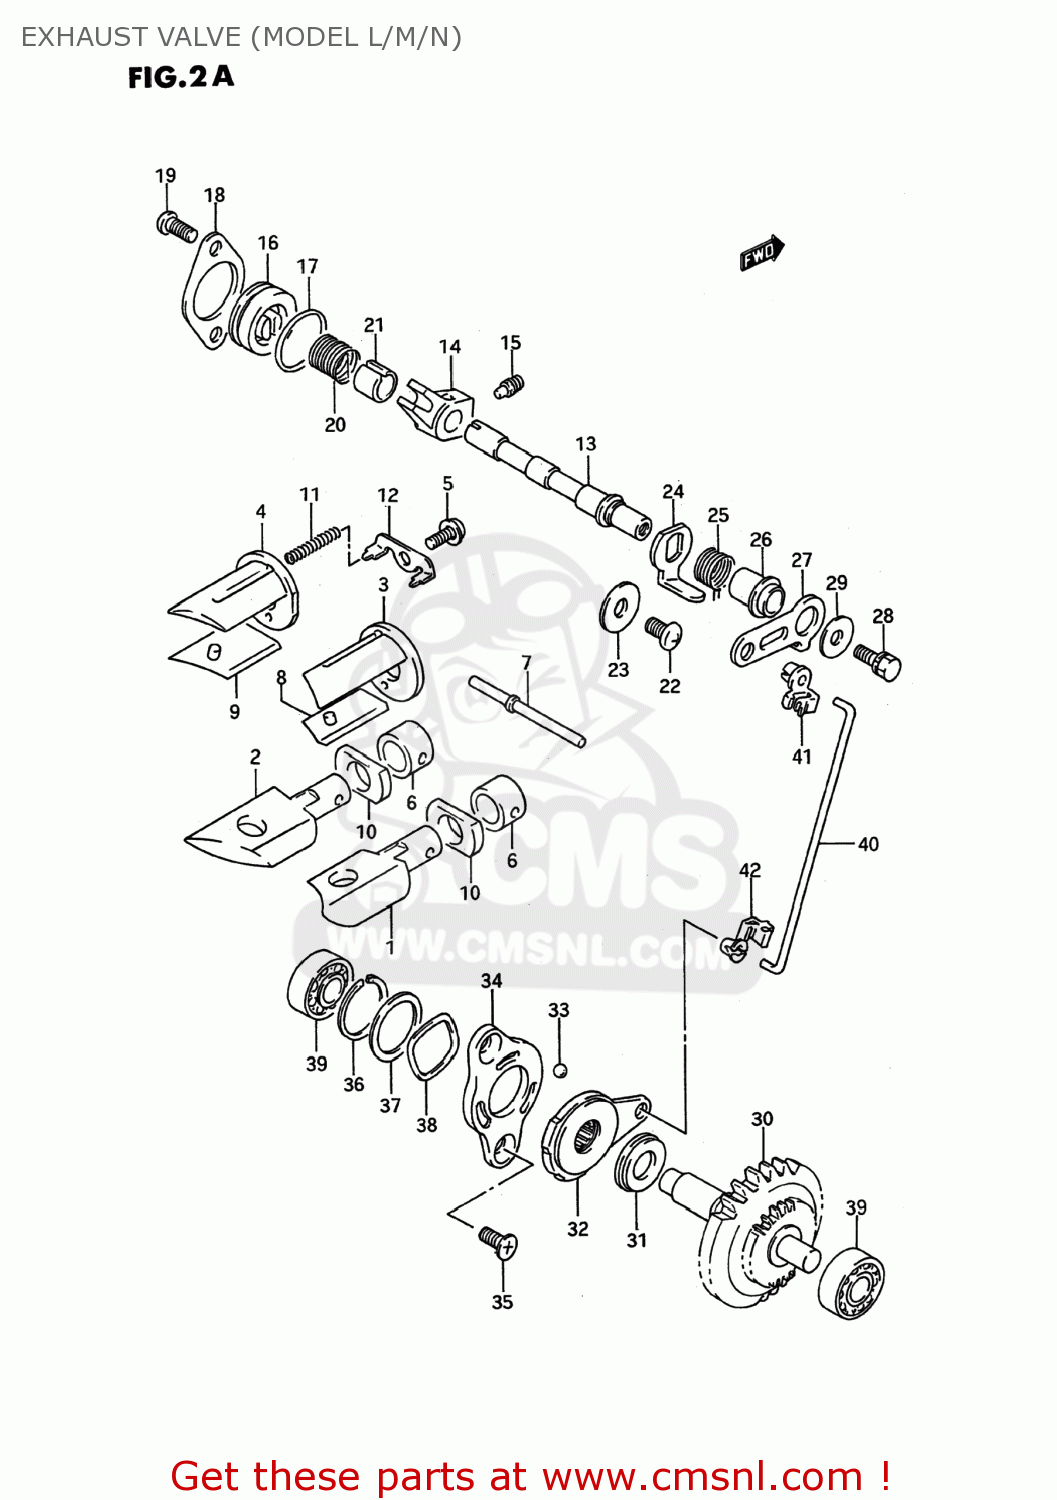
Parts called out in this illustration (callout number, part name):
1	VALVE,EXHAUST,R
2	VALVE,EXHAUST,L
3	GUIDE,EXHAUST VALVE,R
4	GUIDE,EXHAUST VALVE,L
5	SCREW
6	HOLDER,EXHAUST VALVE
7	PIN,EXHAUST VALVE 48.5MM
8	VALVE,EXHAUST NO.2,R
9	VALVE,EXHAUST NO.2,L
10	SPACER,EXHAUST VALVE NO.2
11	SPRING
12	STOPPER,EXHAUST VALVE
13	SHAFT,EXHAUST VALVE
14	ARM,EXHAUST VALVE SHAFT
15	SCREW(6X10)
16	CAP,EXHAUST VALVE
17	O RING(D:1.9,ID:22.6)
18	RETAINER,EXHAUST VALVE
19	SCREW
20	SPRING
21	SPACER,EXHAUST VALVE SPRING
22	SCREW
23	WASHER
24	LEVER,EXHAUST VALVE NO
25	SPRING
26	SPACER,EXHAUST VALVE
27	LEVER,EXHAUST VALVE NO.1
28	BOLT
29	WASHER (5.5X16X1.2)
30	GOVERNOR ASSY,EXHAUST VALVE
31	BEARING(10X22X2.8)
32	ACTUATOR,EXHAUST VALVE
33	BALL
34	STARTER,EXHAUST VALVE ACTUATOR
35	SCREW(5X10)
36	CIRCLIP
37	SHIM(19.1X25X0.3)
38	WASHER
39	BEARING(8X22X7)
40	ROD,EXHAUST VALVE
41	BUSH,EXHAUST VALVE ROD NO.1
42	BUSH,EXHAUST VALVE ROD NO.2
